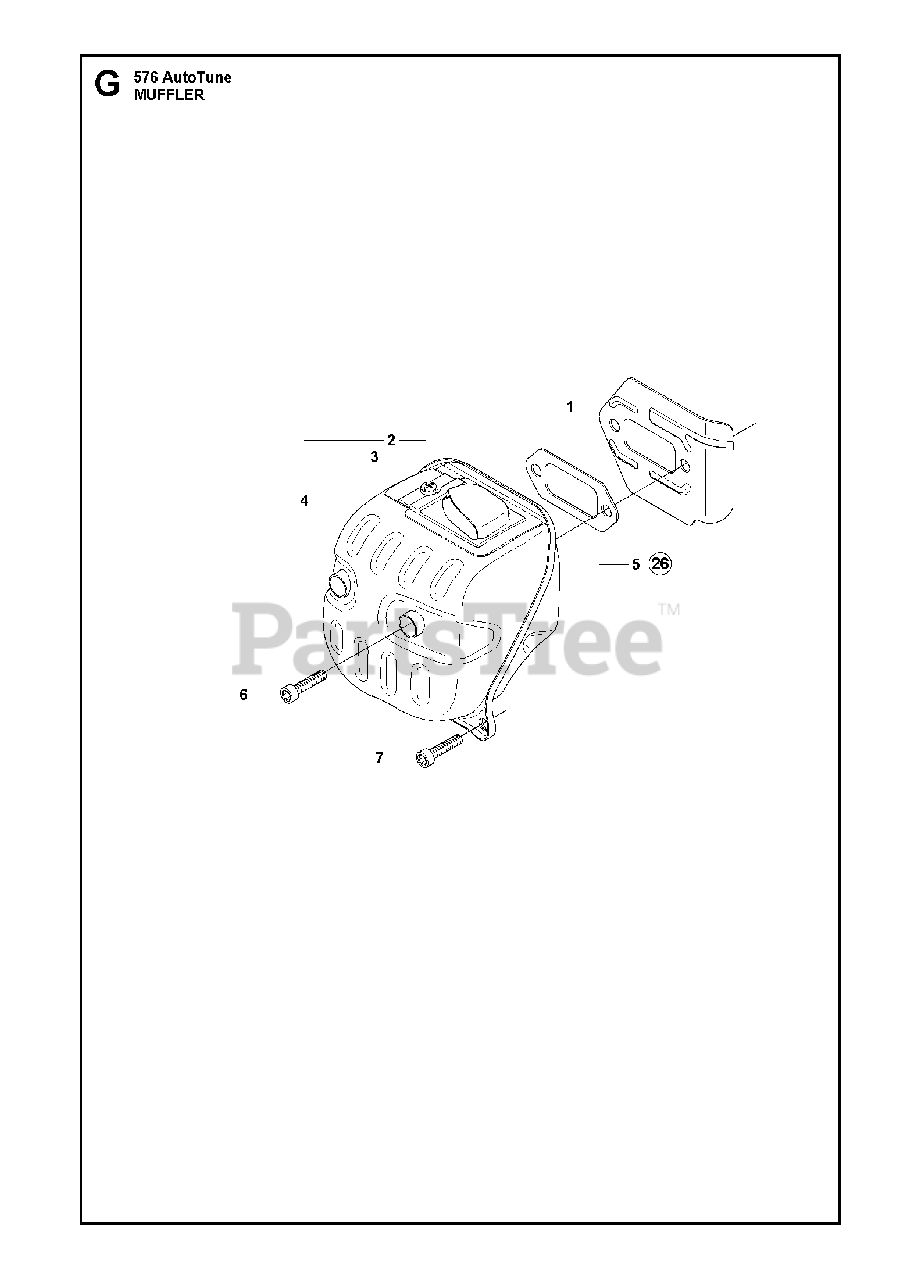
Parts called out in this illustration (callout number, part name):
2	SCREW
3	SCREEN
4	MUFFLER ASSY (FF CE)
4	MUFFLER ASSY (DF US)
5	GASKET
6	SCREW MC6S 6X20
26	GASKET KIT
